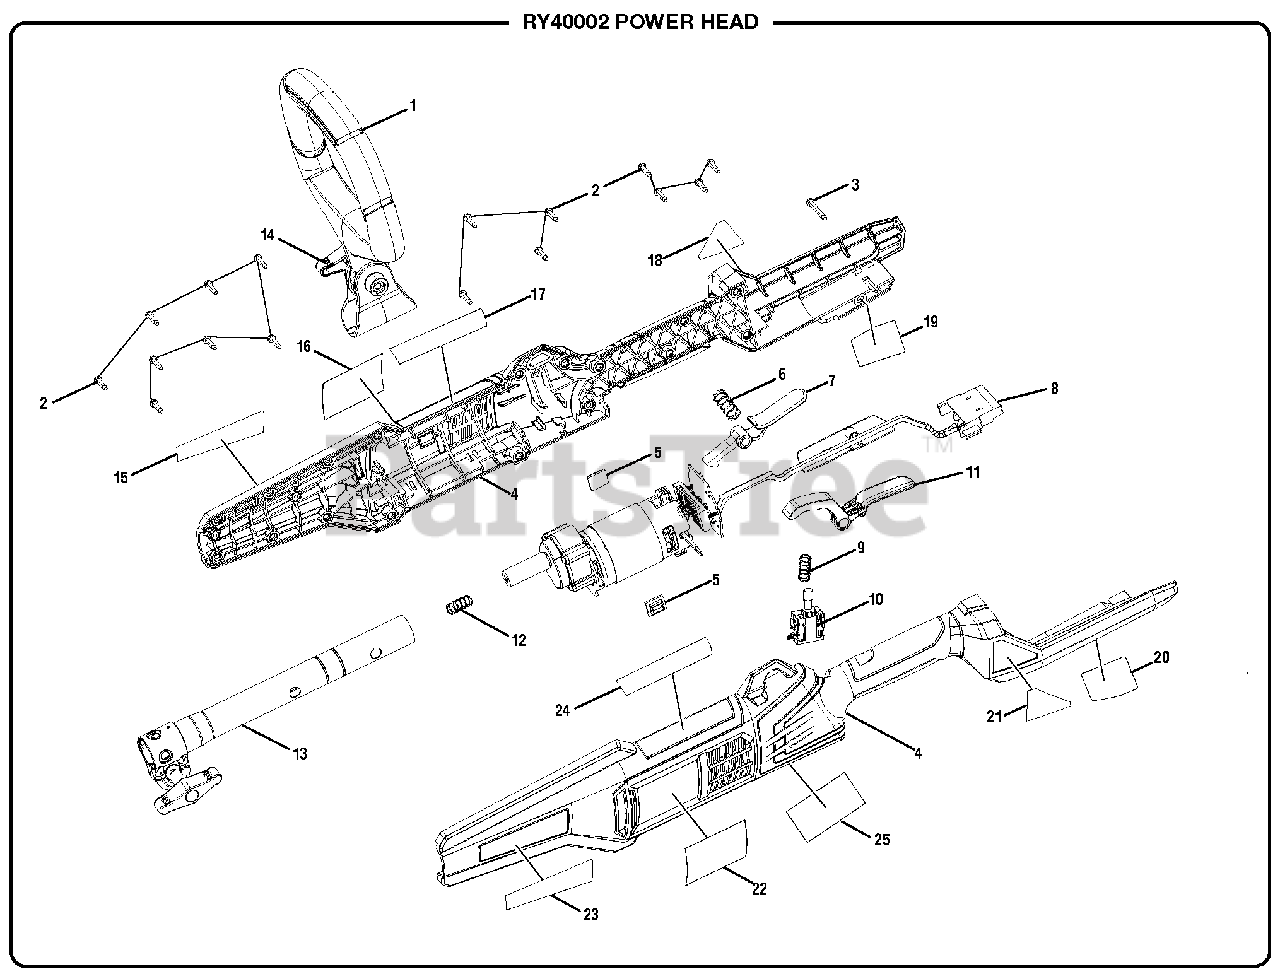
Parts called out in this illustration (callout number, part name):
1	Front Handle Assembly
2	Screw (M4 x 16 mm, T15 Torx Pan Hd.)
3	Screw (M4 x 30 mm, T15 Torx Pan Hd.)
4	Rear Handle Assembly
5	Rubber Bumper
6	Compression Spring (Trigger Lock)
7	Trigger Lock-Out Lever
8	Motor & Gear Box Assembly
9	Compression Spring (Trigger)
10	Switch (Variable Speed)
11	Switch Trigger Spring
12	Compression Spring
13	Upper Boom Assembly
14	Knob Assembly
15	Expandit Logo Label (Right)
16	Logo Label (Right)
17	Warning Label
18	40 Volt Label (Right)
19	Warning Label (Spanish)
20	Warning Label (French)
21	40 Volt Label (Left)
22	Logo Label (Left)
23	Expandit Logo Label (Left)
24	Icon Warning Label
25	Data Label
